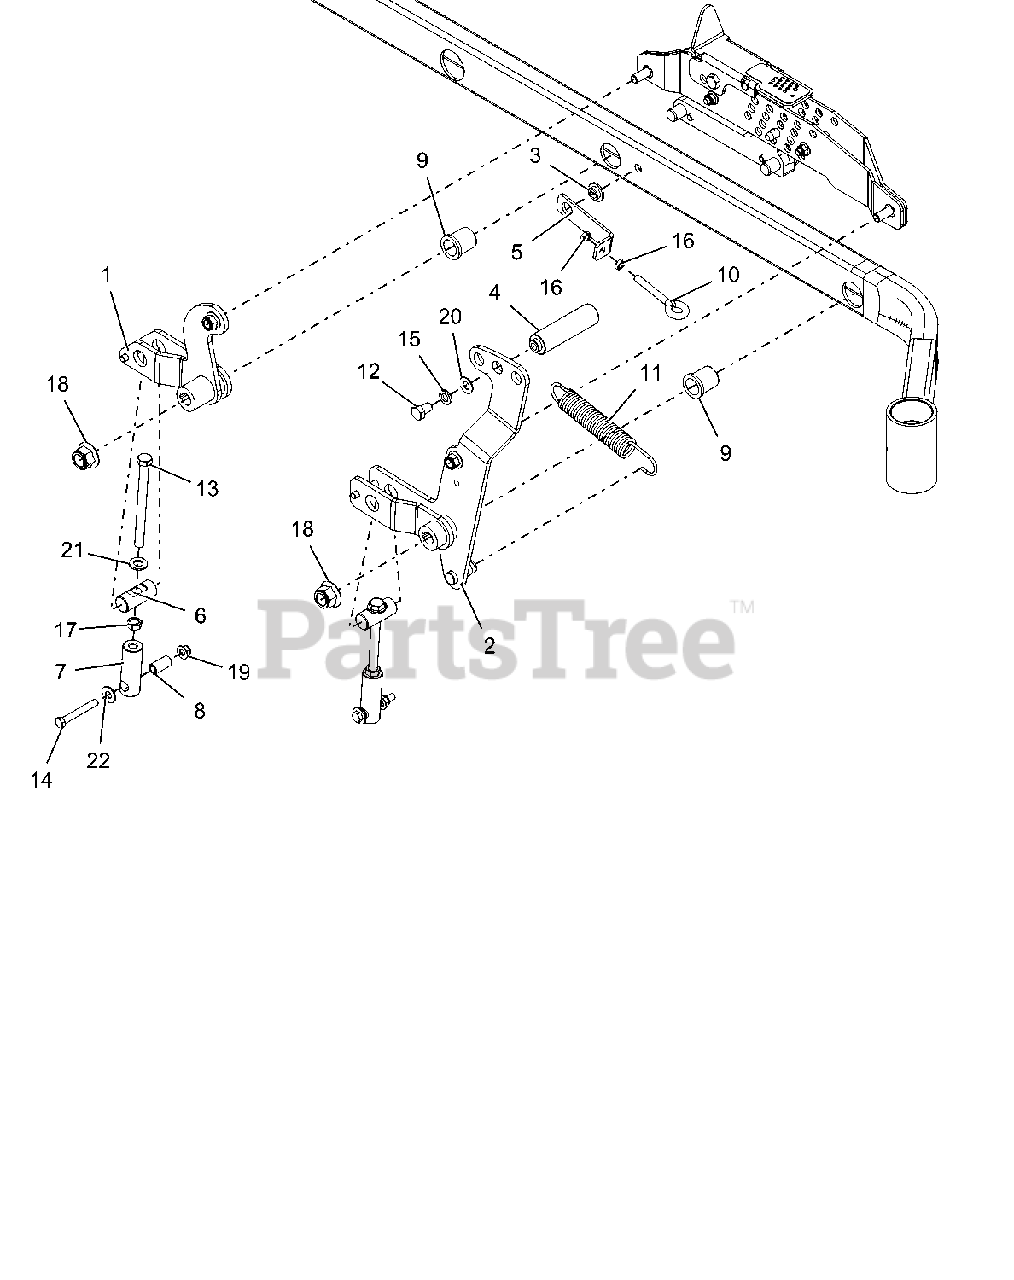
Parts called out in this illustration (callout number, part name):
1	REAR RH DECK LIFT ARM WMT- LF
2	FRT RH DECK LIFT ARM WMT- LF
3	BSHG-FLG .515X.750X.395X1.120
4	FOOT PEG, DECK LIFT
5	SPRING ANCHOR BRACKET - RED
6	PIN, DECK LIFT
7	LINK, DECK LIFT
8	SPACER, DECK LEVELING
9	BSHG-FLG 1.00X1.25X1.50X1.50
10	BLT-EYE .375-16X2.50 YWZC
11	SG-TENS .162X1.25X8.25 WLD 25
12	@BLT-HEX .50-13X.75 GR5 YWZC
13	BOLT,.50-13X6.00-2.50 LG THD
14	BLT-HEX .38-16X2.75 GR8 YWZC
15	@WSHR-LK .50X.125 REG YWZC
16	NUT-HEX-JAM .375-16 YWZC
17	NUT-JAM .50-13 YWZC
18	@NUT-LK-NYL-FLG .75-10 YWZC
19	@NUT-LK-NYL-FLG .38-16 YWZC
20	WSHR-FL-STL .505X1.00X.062YWZC
21	FLATWASHER 1/2 SAE HARD 15906
22	@WSHR-FL-STL.438X1.00X.083 YWZ
